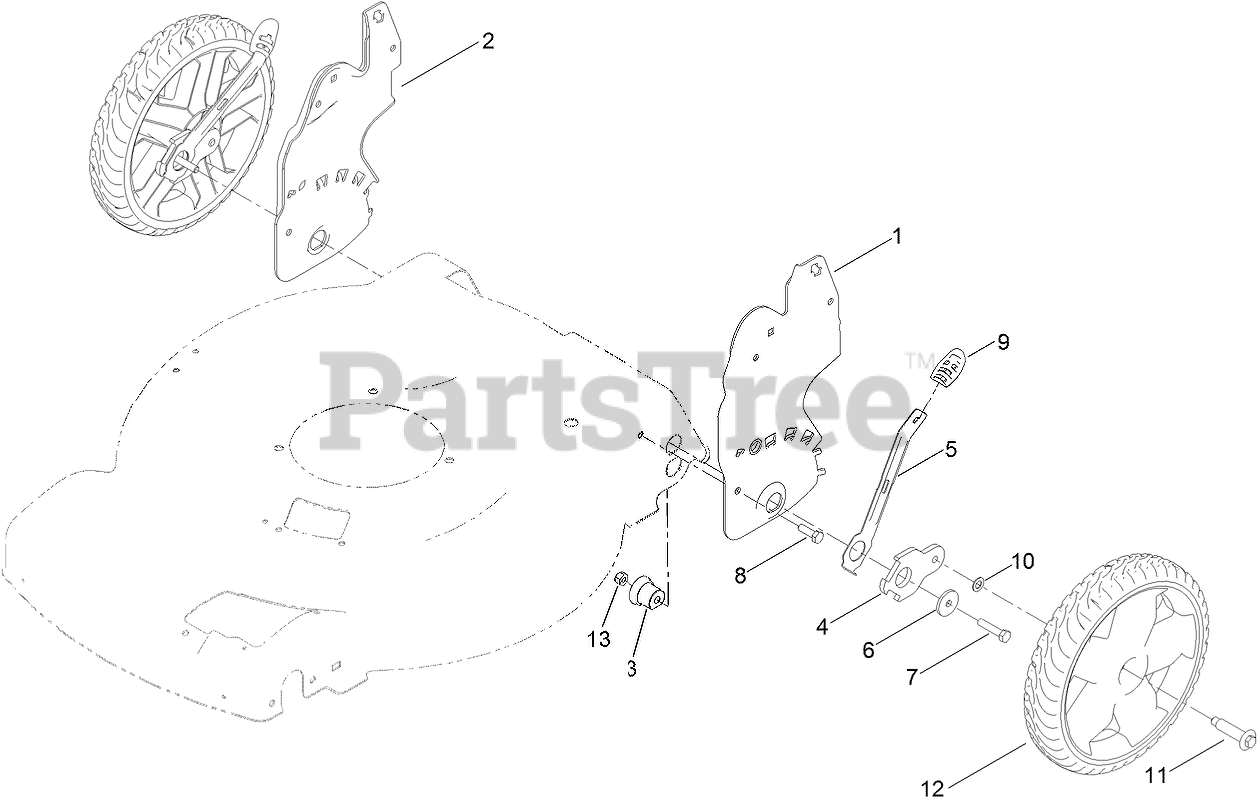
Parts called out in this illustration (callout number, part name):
1	PLATE-HOC, LH
2	PLATE-HOC, RH
3	BUSHING-MOUNT, HOC
4	ARM-PIVOT, REAR
5	ARM-SPRING, REAR
6	WASHER-FLAT
7	SCREW-HH
8	SCREW-HH
9	KNOB-LEVER, HOC
10	WASHER
11	BOLT-SHOULDER
13	NUT-LOCK, NI
